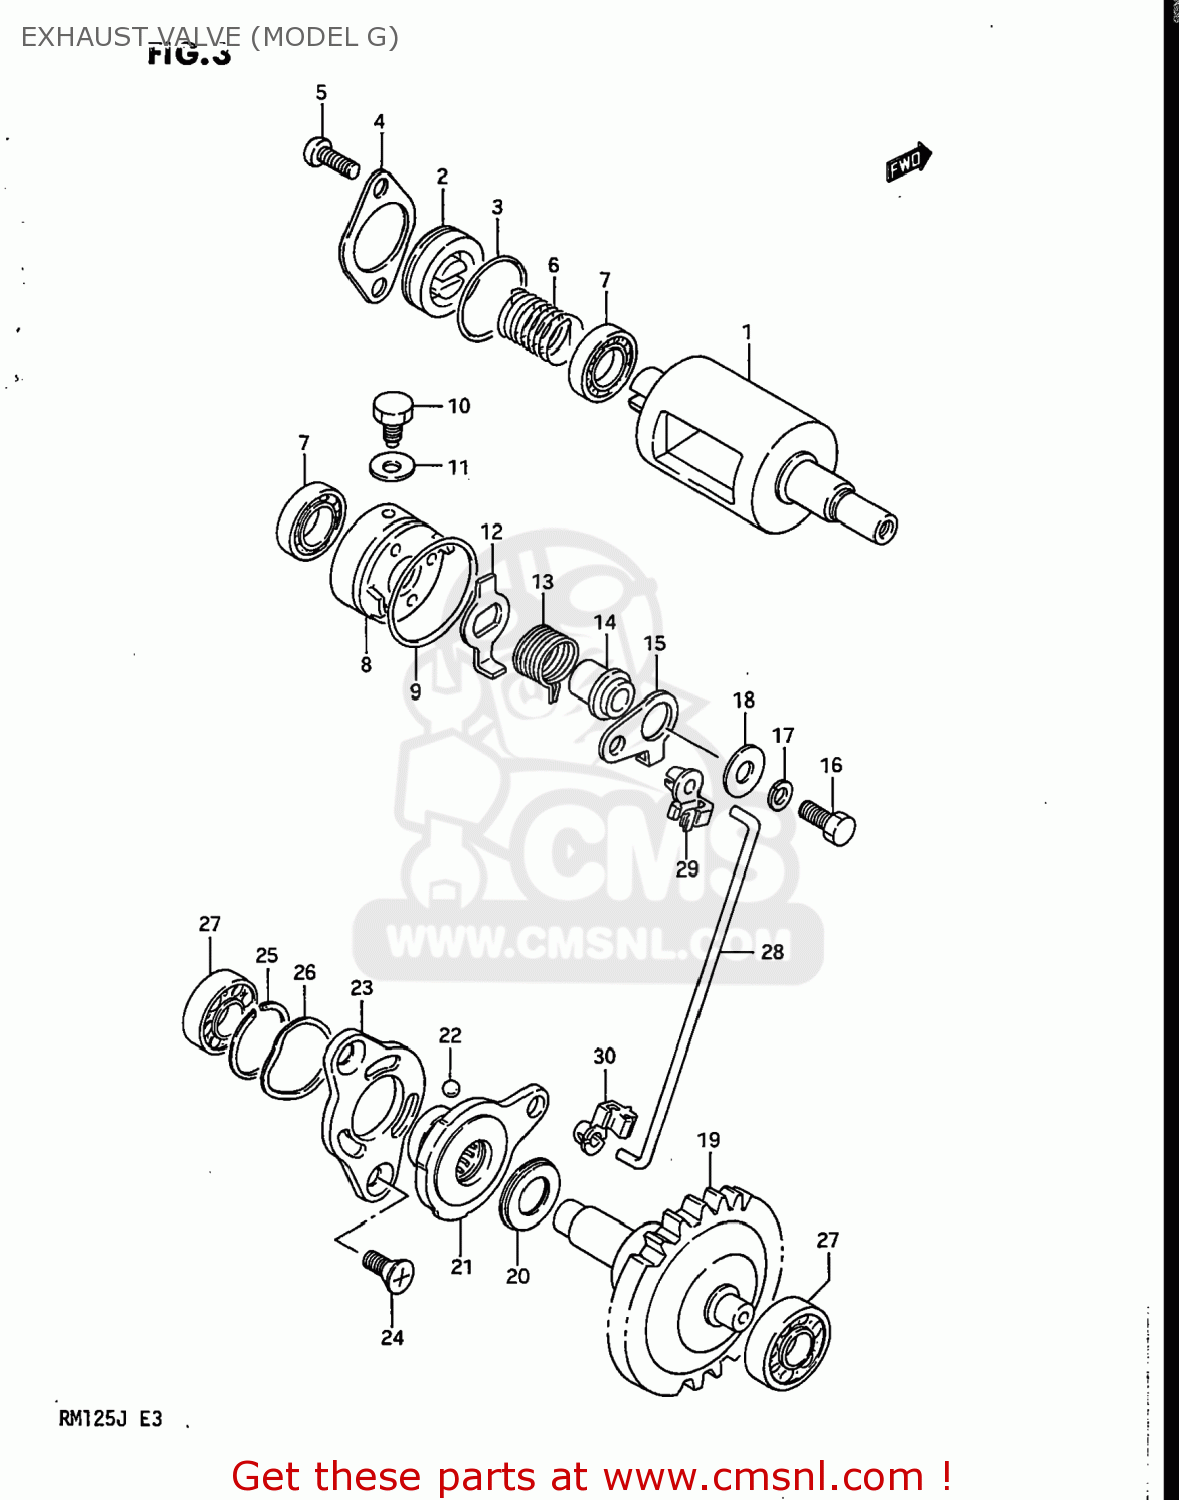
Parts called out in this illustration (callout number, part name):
1	VALVE,EXHAUST
2	CAP,EXHAUST VALVE
3	O RING(D:1.9,ID:22.6)
4	RETAINER,EXHAUST VALVE
5	SCREW
6	SPRING
7	BEARING
8	HOLDER,EXHAUST VALVE
9	O RING(D:2.4,ID:27.7)
10	BOLT
11	GASKET(6.2X11X1).2 (NAS)
12	LEVER,EXHAUST VALVE NO
13	SPRING
14	SPACER,EXHAUST VALVE
15	LEVER,EXHAUST VALVE NO.1
16	BOLT
17	LOCK WASHER
18	WASHER (5.5X16X1.2)
19	GOVERNOR ASSEMBLY,EXHAUST
20	BEARING(10X22X2.8)
21	ACTUATOR,EXHAUST VALVE
22	BALL
23	STATOR,EXHAUST VALVE ACTUATOR
24	SCREW 5X12
25	CIRCLIP
26	WASHER
27	BEARING(8X22X7)
28	ROD,EXHAUST VALVE
29	BUSH,EXHAUST VALVE ROD NO.1
30	BUSH,EXHAUST VALVE ROD NO.2
